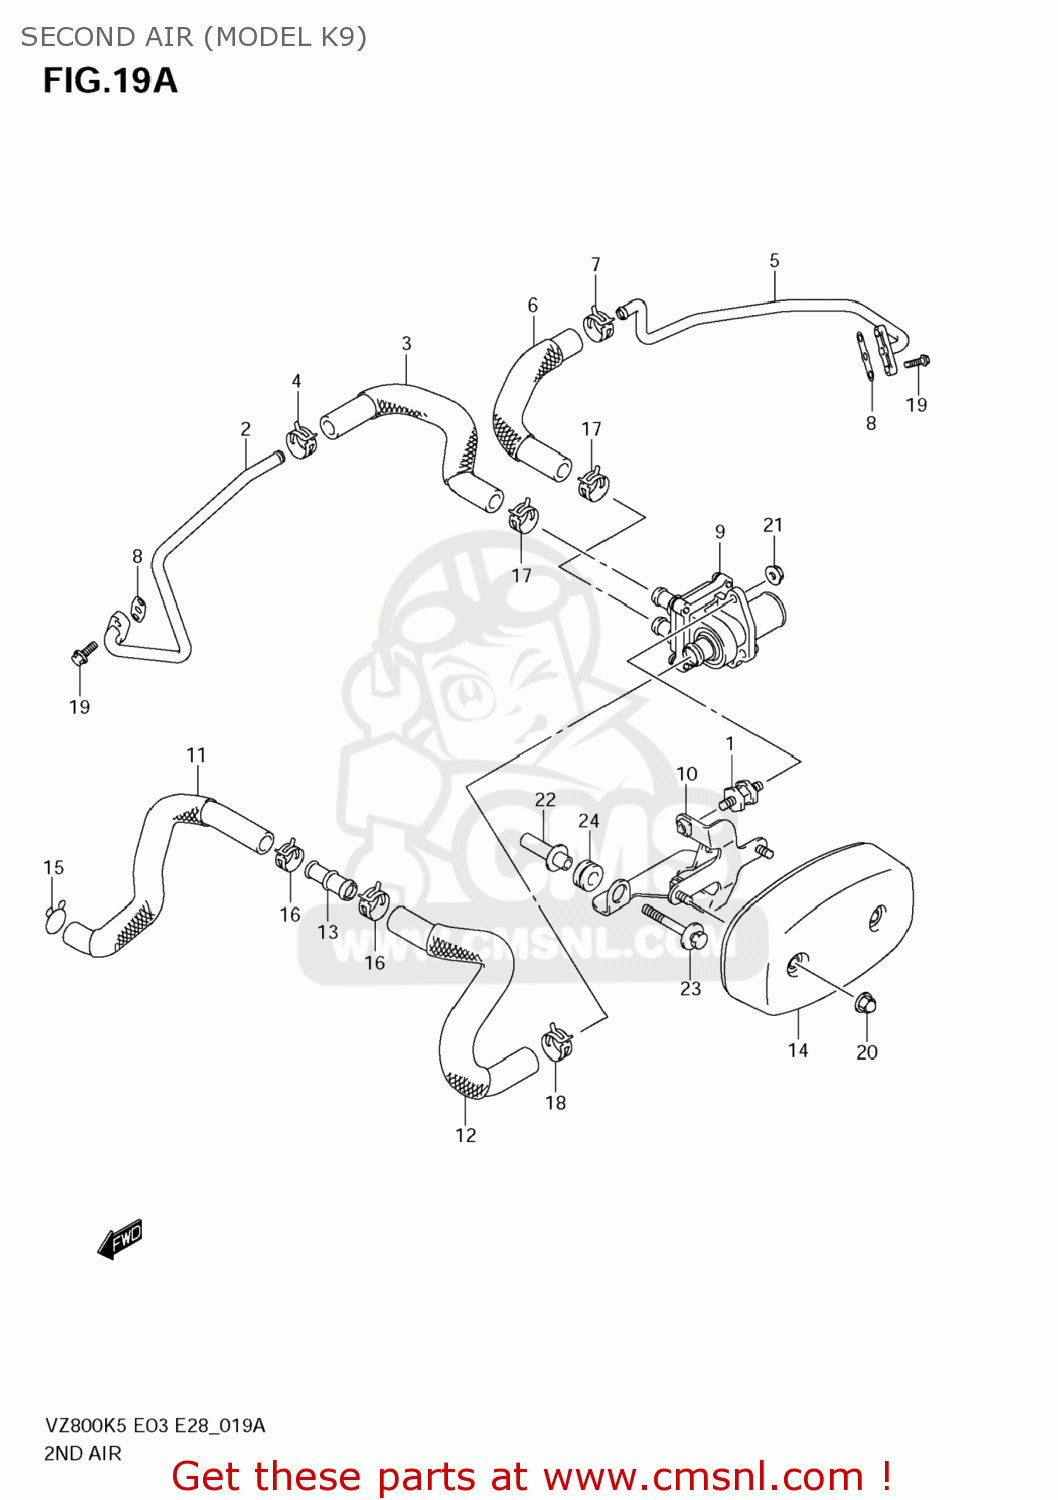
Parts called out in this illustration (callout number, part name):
1	BOLT,CUSHION
2	PIPE,2ND AIR FR
3	HOSE,2ND AIR VALVE FR
4	CLIP
5	PIPE,2ND AIR RR
6	HOSE,2ND AIR VALVE RR
7	CLIP
8	GASKET,2ND AIR PIPE (NAS)
9	VALVE ASSY,2ND
10	BRACKET,2ND AIR SPRT
11	HOSE,2ND AIR CLEANER
12	HOSE,2ND AIR CLEANER
13	JOINT,2ND AIR CLEANER HOSE
14	COVER,2ND AIR VALVE
15	CLIP
16	CLIP
17	CLIP
18	CLIP
19	BOLT
20	NUT
21	NUT
22	SPACER,2ND AIR SPRT BRKT
23	BOLT(6X55)
24	CUSHION
